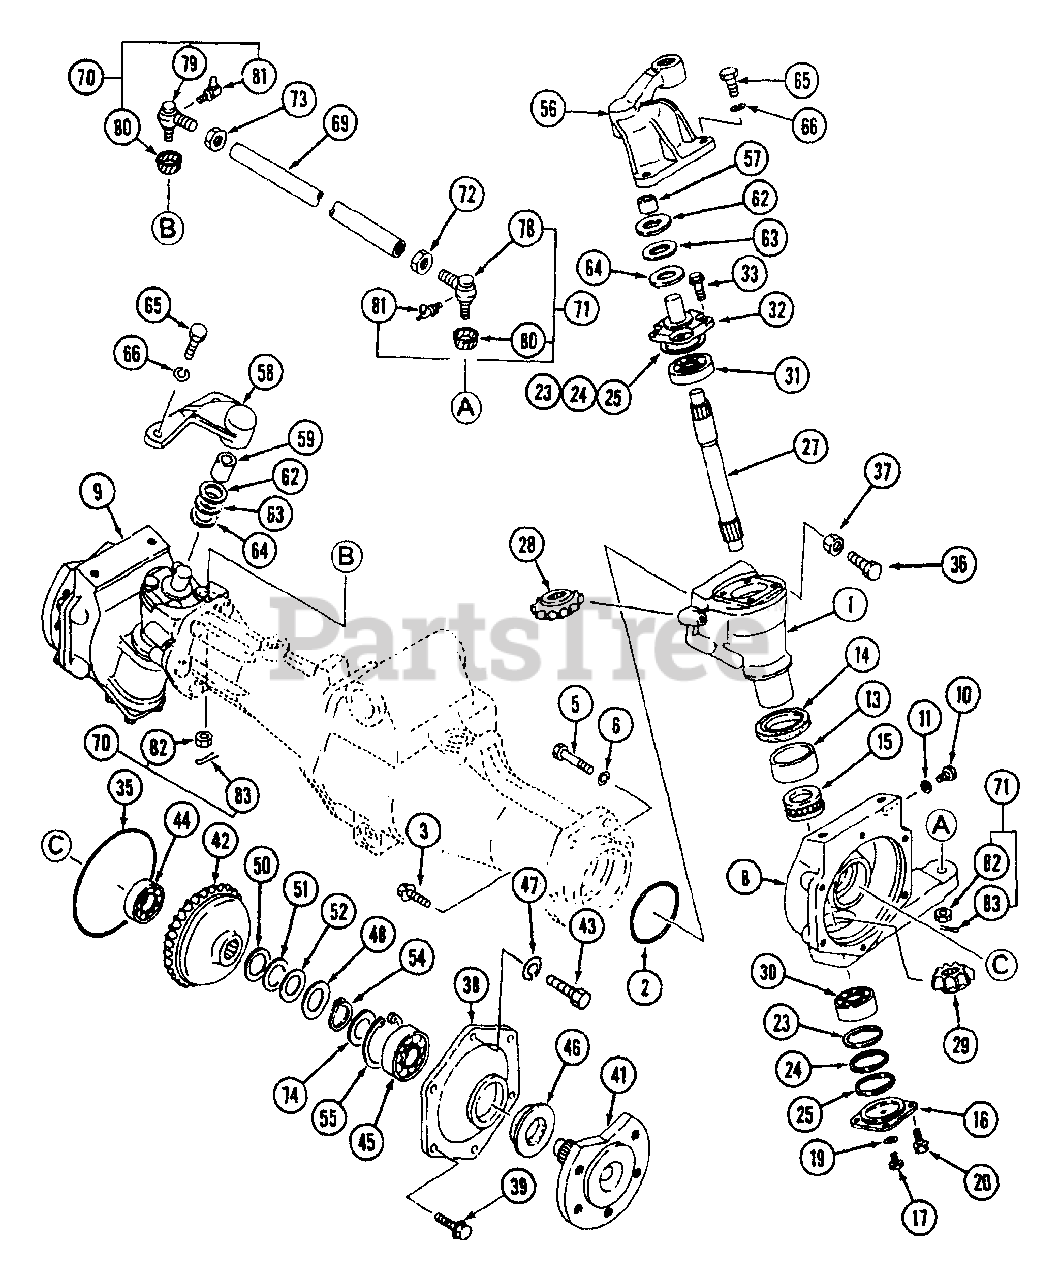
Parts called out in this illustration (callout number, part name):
1	Case, Kingpin
8	Case Final L.H.
9	Case Final R.H.
56	Knuckle Arm L.H.
58	Knuckle Arm R.H.
62	Liner, Thrust C t=1.4
63	Liner,Thrust D t=1.2
64	Liner, Thrust E t=0.8
70	End Ass'y - Tie Rod R.H. Side (L.H. Thread)
71	End Ass'y - Tie Rod L.H. Side (R.H. Thread)
72	Nut (R.H. Thread) M17
73	Nut (L.H. Thread) M17
80	Cover, Dust
81	Nipple, Grease
